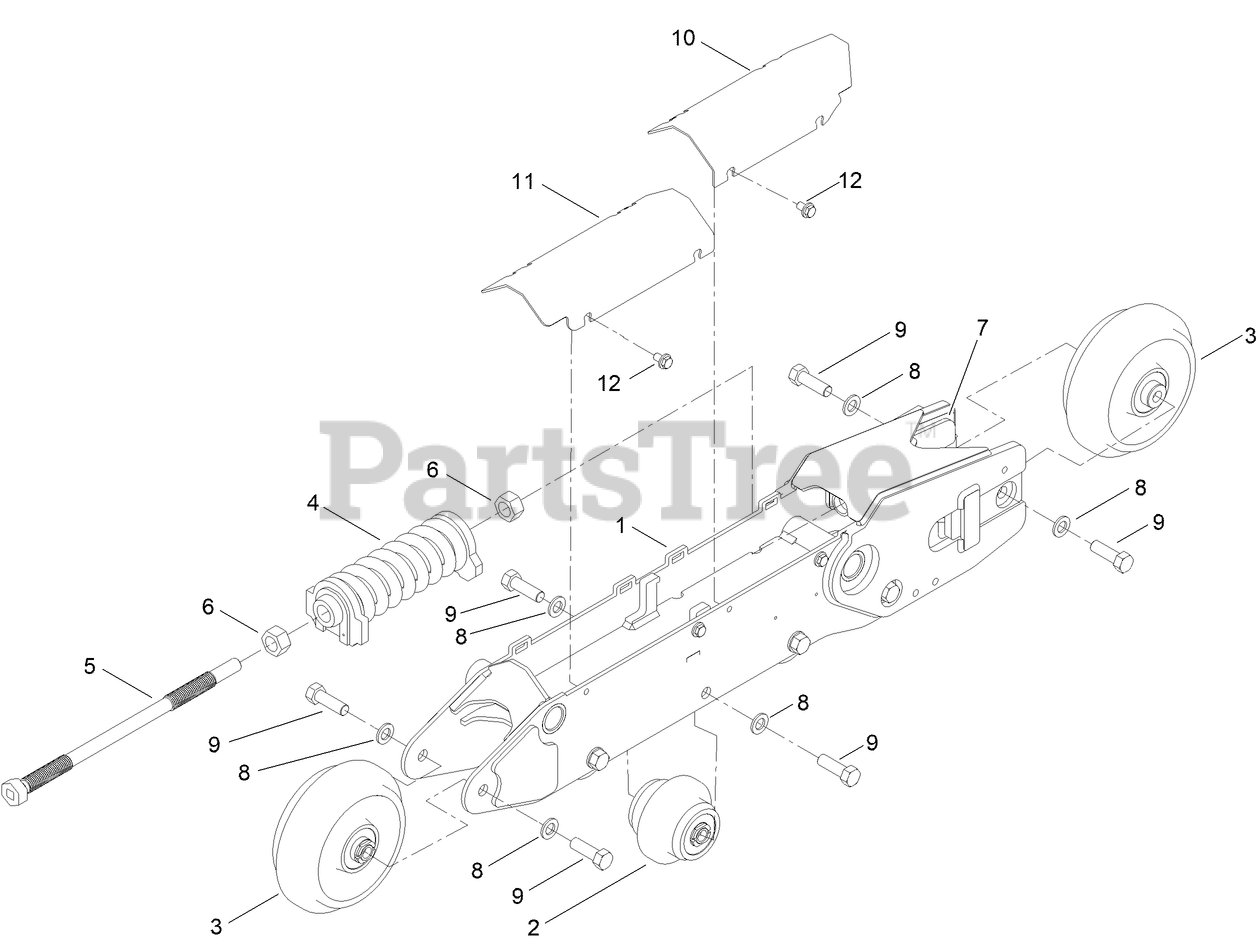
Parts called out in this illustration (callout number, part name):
1	FRAME-TRACK RH
2	WHEEL-ASM CAMSO
3	WHEEL-ASM TENSIONER
4	KIT-SPRING TENSION
5	SCREW-TENSIONER
6	NUT-HEX
7	YOKE-TENSIONER
8	WASHER
9	SCREW-HH
10	PLATE-COVER RH
11	PLATE-COVER RH
12	SCREW-HHF
